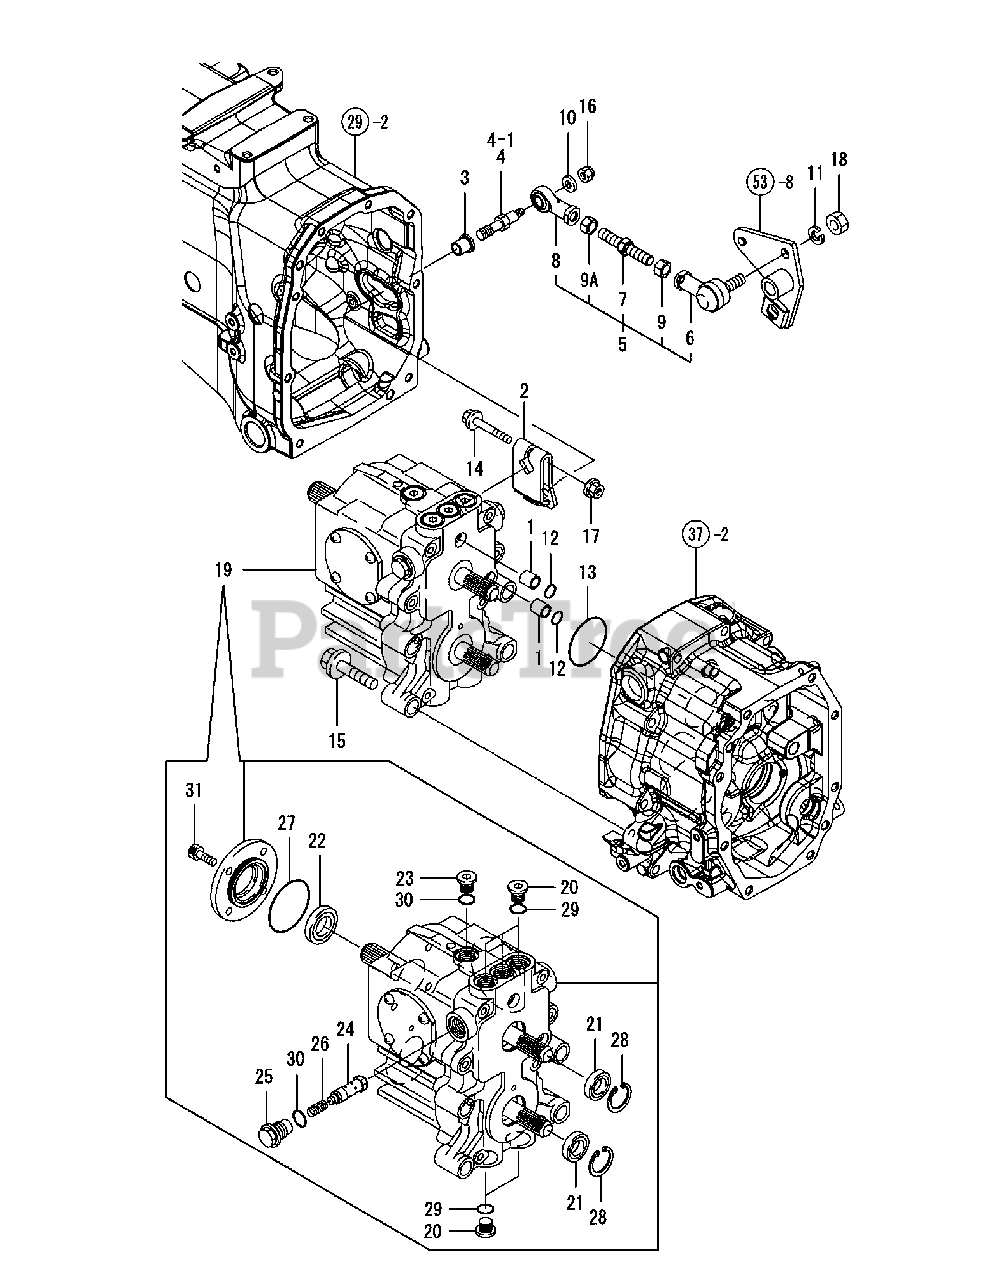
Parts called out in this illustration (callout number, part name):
1	COLLAR, 12X16X17
2	ARM, TRUNNION CMP
3	COLLAR, TRUNNION
4	PIN,TRUNNION
5	ROD END ASSY, HST
10	WASHER 8, POLISHED
11	SPRING WASHER 12
12	O-RING 1A P-16.0
13	O-RING 1A G-60.0
14	BOLT M 8X 55 PLATED
16	U-NUT M 8 PLATED
22	SEAL 25*45*8.OIL
24	NCR, VALVE+0.7
26	SPRING (CHECK VALVE)
29	O-RING 1B P-14.0
30	O-RING 1B P-18.0
